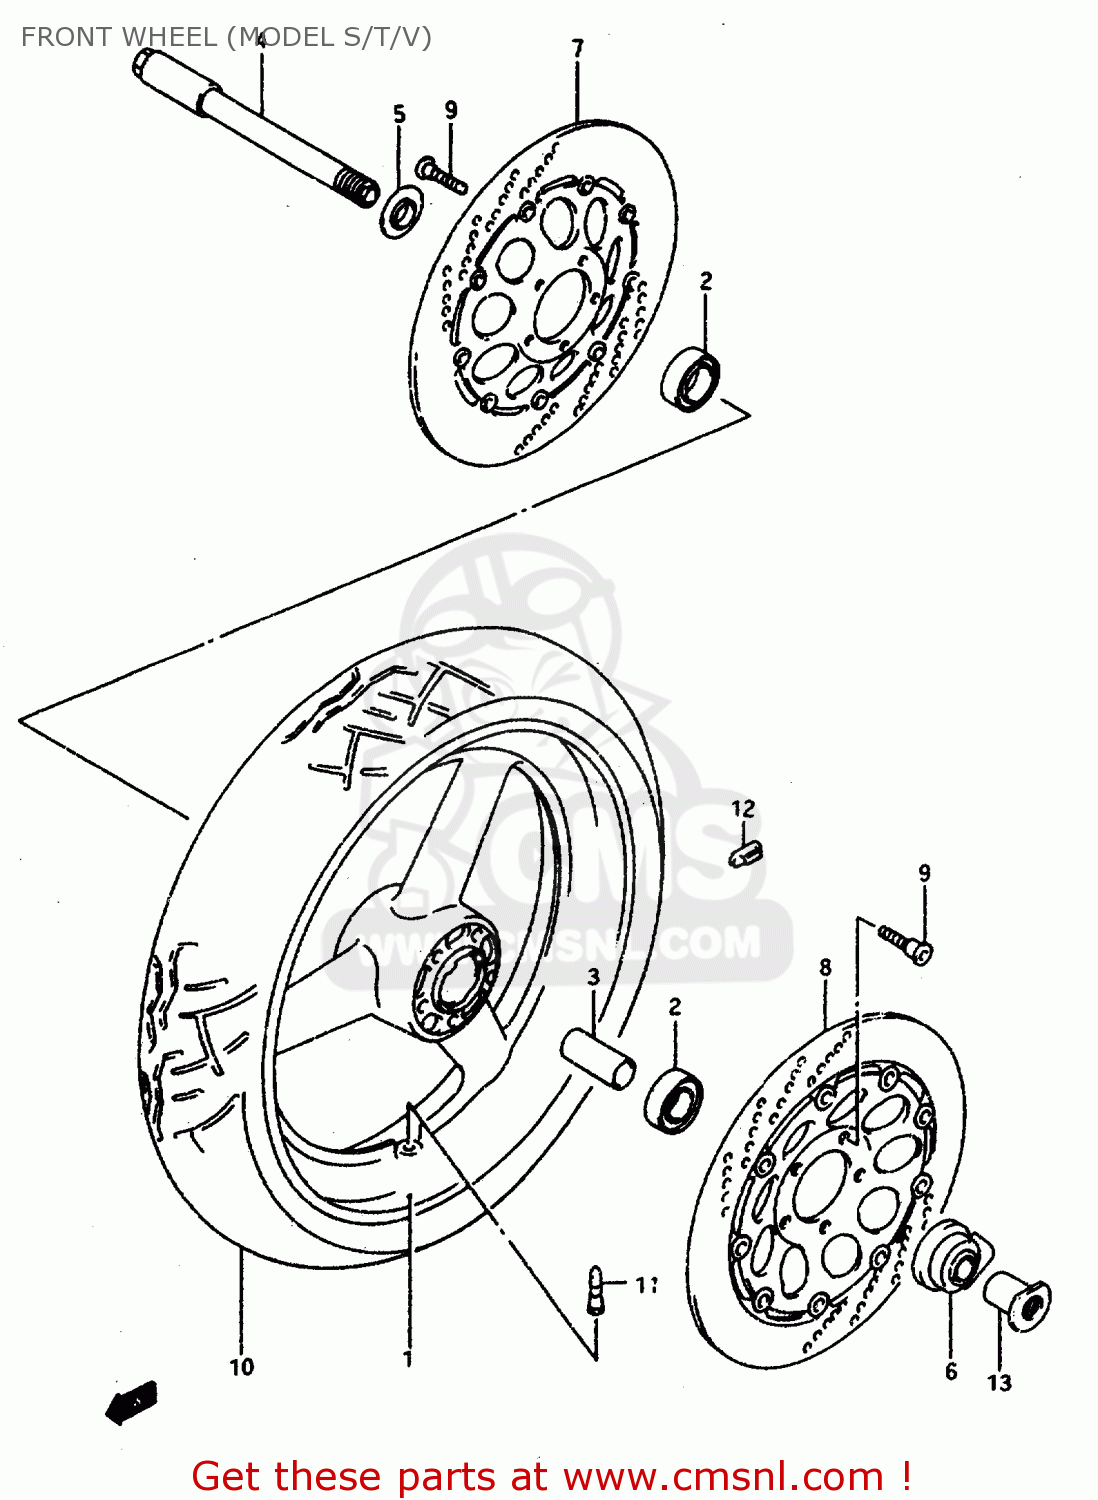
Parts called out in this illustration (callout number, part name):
1	WHEEL,FRONT
2	BEARING
3	SPACER(20.8X27.2X74)
4	AXLE,FR
5	SPACER,FR HUB BEARING,R
6	BOX ASSY,SPEEDOMETER GEAR
7	DISC,FR BRAKE,R
8	DISC,FR BRAKE,L
9	BOLT 8X33
10	TIRE,FRONT
11	VALVE ASSEMBLY,WHEEL,TR412
12	BALANCER,WHEEL
13	NUT,FR AXLE
